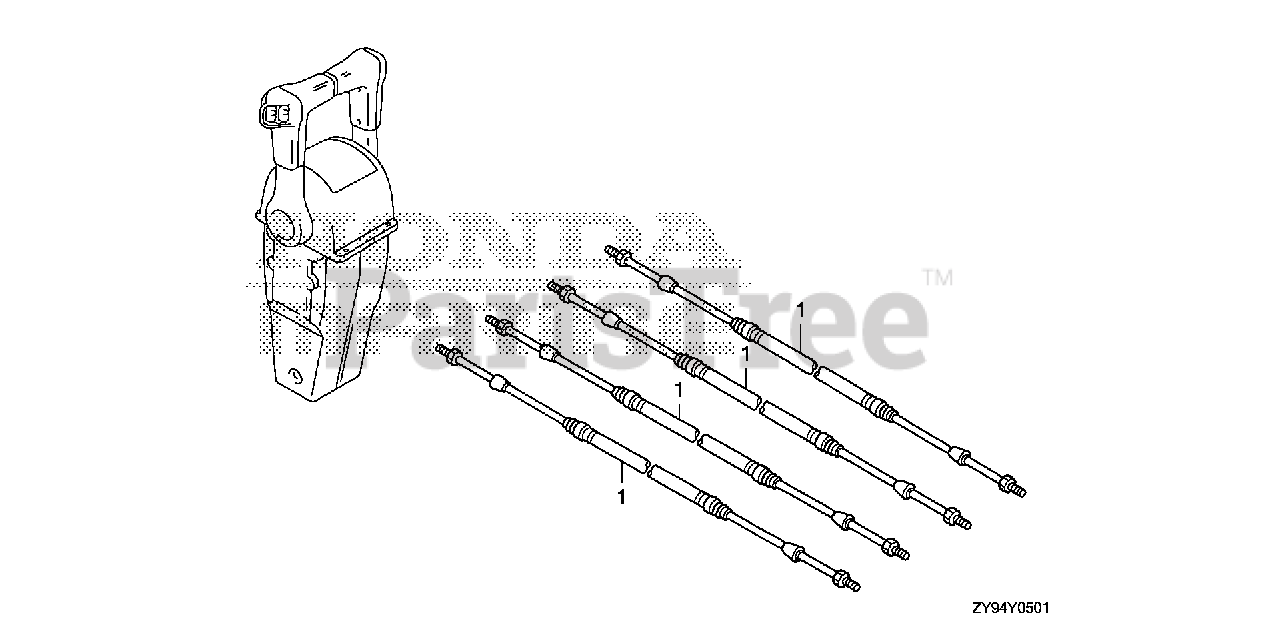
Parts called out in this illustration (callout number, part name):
1	CABLE, REMOTE CONTROL (10'') (LOW FRICTION)
1	CABLE ASSY., PUSH-PULL (33C-5FT)
1	CABLE, REMOTE CONTROL (11'') (LOW FRICTION)
1	CABLE ASSY., PUSH-PULL (33C-6FT)
1	CABLE, REMOTE CONTROL (12'') (LOW FRICTION)
1	CABLE ASSY., PUSH-PULL (33C-7FT)
1	CABLE, REMOTE CONTROL (13'') (LOW FRICTION)
1	CABLE ASSY., PUSH-PULL (33C-8FT)
1	CABLE, REMOTE CONTROL (14'') (LOW FRICTION)
1	CABLE ASSY., PUSH-PULL (33C-9F T)
1	CABLE, REMOTE CONTROL (15'') (LOW FRICTION)
1	CABLE ASSY., PUSH-PULL (33C-10FT)
1	CABLE, REMOTE CONTROL (16'') (LOW FRICTION) (NOT AVAILABLE)
1	CABLE ASSY., PUSH-PULL (33C-11FT)
1	CABLE, REMOTE CONTROL (17'') (LOW FRICTION)
1	CABLE ASSY., PUSH-PULL (33C-12 FT)
1	CABLE, REMOTE CONTROL (18') (LOW FRICTION) (NOT AVAILABLE)
1	CABLE ASSY., PUSH-PULL (33C-13 FT)
1	CABLE, REMOTE CONTROL (1 9'') (LOW FRICTION)
1	CABLE ASSY., PUSH-PULL (33C-14FT)
1	CABLE, REMOTE CONTROL (20'') (LOW FRICTION) (NOT AVAILABLE)
1	CABLE ASSY., PUSH-PULL (33C-15 FT)
1	CABLE, REMOTE CONTROL (21') (LOW FRICTION)
1	CABLE ASSY., PUSH-PULL (33C-16FT)
1	CABLE, REMOTE CONTROL (22') (LOW FRICTION) (NOT AVAILABLE)
1	CABLE ASSY., PUSH-PULL (33C-17 FT)
1	CABLE, REMOTE CONTROL (2 3'') (LOW FRICTION)
1	CABLE ASSY., PUSH-PULL (33C-18 FT)
1	CABLE, REMOTE CONTROL (24') (LOW FRICTION) (NOT AVAILABLE)
1	CABLE ASSY., PUSH-PULL (33C-19FT)
1	CABLE, REMOTE CONTROL (25') (LOW FRICTION)
1	CABLE ASSY., PUSH-PULL (33C-20FT)
1	CABLE, REMOTE CONTROL (26') (LOW FRICTION)
1	CABLE ASSY., PUSH-PULL (33C-21FT)
1	CABLE, REMOTE CONTROL (27') (LOW FRICTION)
1	CABLE ASSY., PUSH-PULL (33C-22FT)
1	CABLE, REMOTE CONTROL (28') (LOW FRICTION) (NOT AVAILABLE)
1	CABLE ASSY., PUSH-PULL (33C-23FT)
1	CABLE, REMOTE CONTROL (2 9') (LOW FRICTION)
1	CABLE ASSY., PUSH-PULL (33C-24FT)
1	CABLE, REMOTE CONTROL (30') (LOW FRICTION) (NOT AVAILABLE)
1	CABLE ASSY., PUSH-PULL (33C-25FT)
1	CABLE, REMOTE CONTROL (31') (LOW FRICTION)
1	CABLE ASSY., PUSH-PULL (33C-26FT)
1	CABLE, REMOTE CONTROL (32') (LOW FRICTION) (NOT AVAILABLE)
1	CABLE ASSY., PUSH-PULL (33C-27FT)
1	CABLE, REMOTE CONTROL (33') (LOW FRICTION)
1	CABLE ASSY., PUSH-PULL (33C-28FT)
1	CABLE, REMOTE CONTROL (34') (LOW FRICTION)
1	CABLE ASSY., PUSH-PULL (33C-29FT)
1	CABLE, REMOTE CONTROL (35') (LOW FRICTION)
1	CABLE ASSY., PUSH-PULL (33C-30FT)
1	CABLE ASSY., PUSH-PULL (33C-31FT)
1	CABLE ASSY., PUSH-PULL (33C-32FT)
